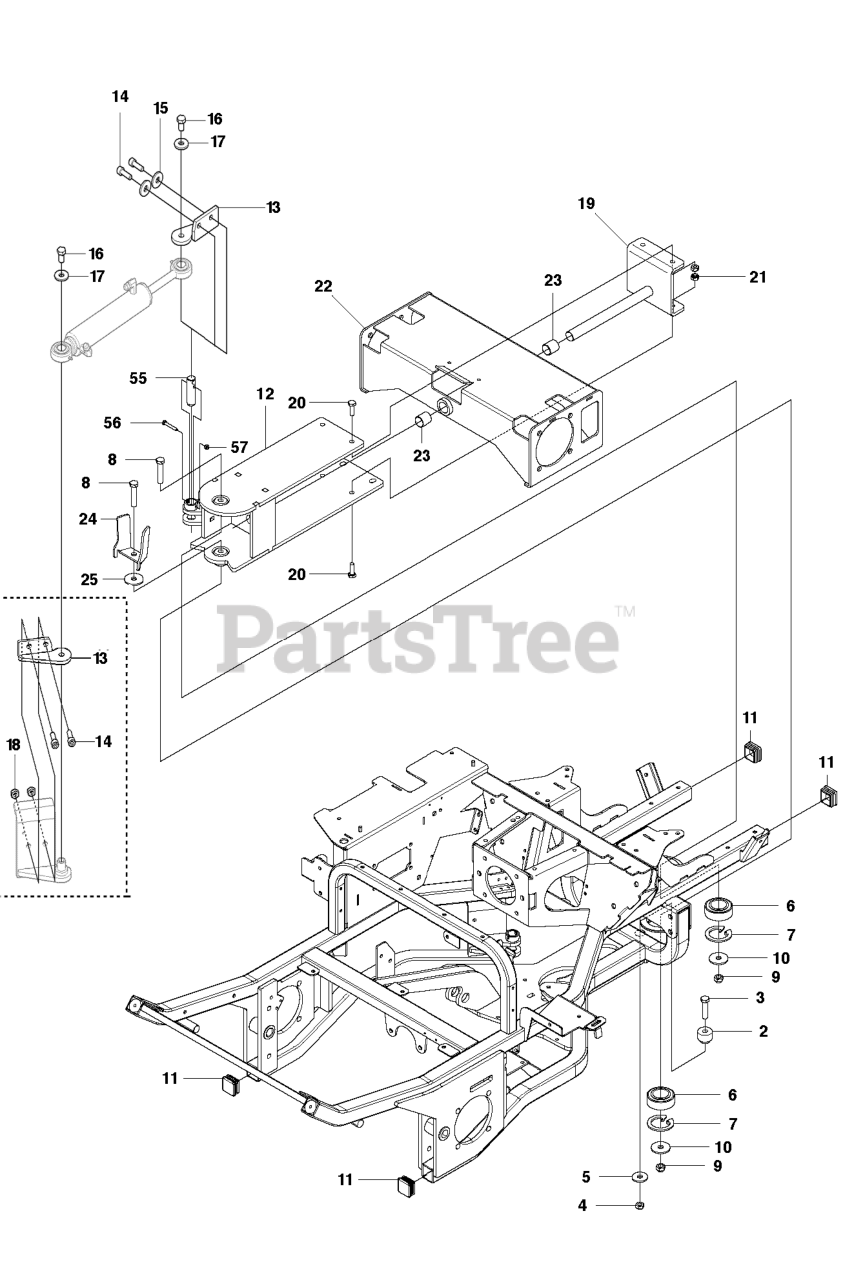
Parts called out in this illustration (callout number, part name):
2	STOP SLEEVE STEERING STOP
12	FRAME REAR
15	WASHER
16	SCREW
18	NUT
19	SWING AXLE
21	NUT
23	BUSHING
24	GUIDE PLATE HYDRAULIC HOSES
57	LOCKNUT M6
